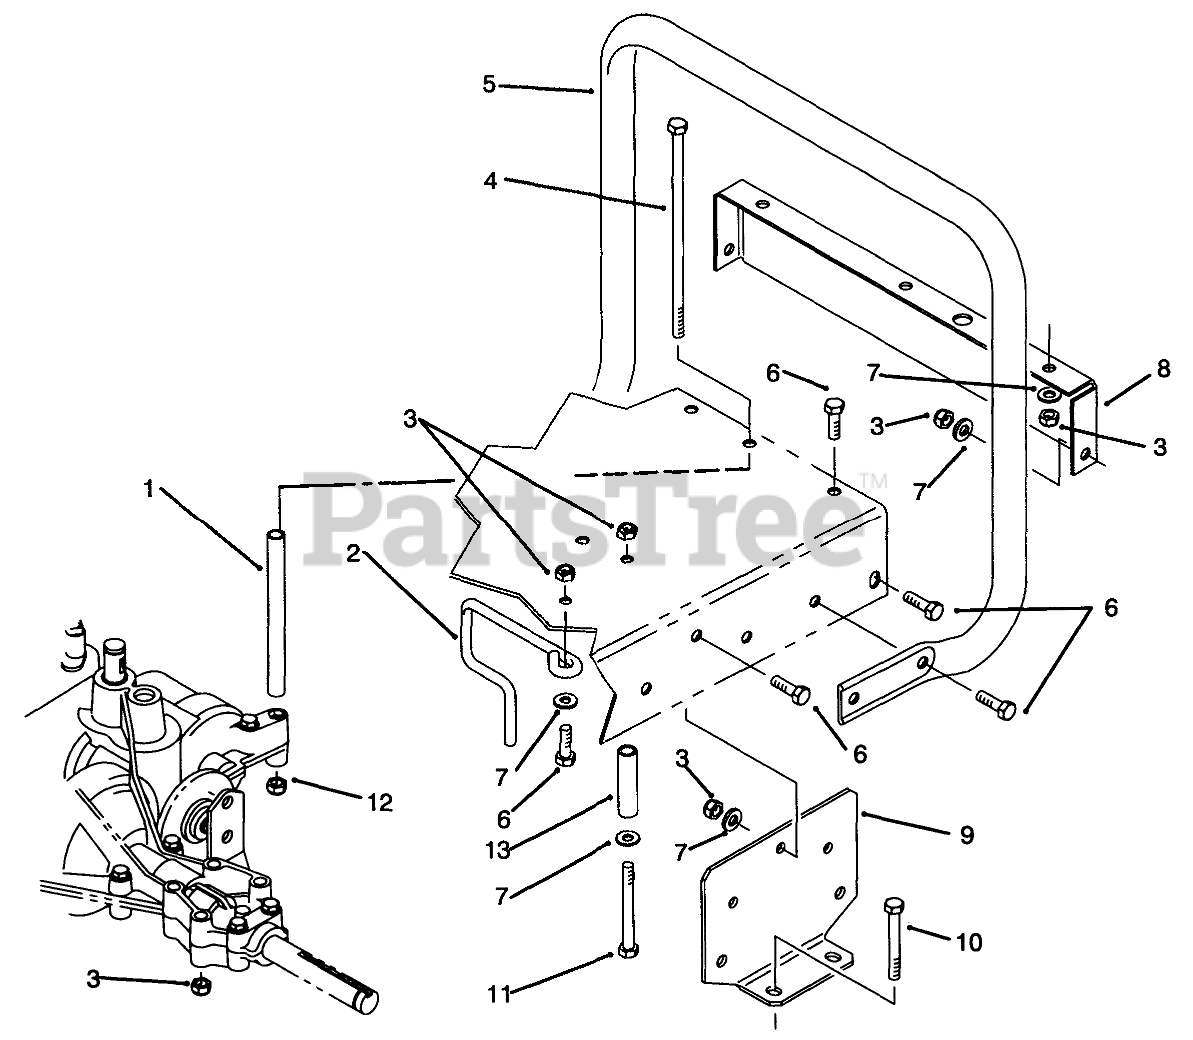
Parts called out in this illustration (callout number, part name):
1	SPACER-TRANSAXLE SUPT
2	GUIDE-ENG BELT
3	NUT-LOCK, NI
4	SCREW-HH
5	Standbar
6	SCREW-HH
7	WASHER-PLAIN
8	Frame-Rear
9	Support-Axle
10	SCREW-HH
11	SCREW-HH
12	NUT-LOCK, NI
13	SPACER-SPLIT TUBE
